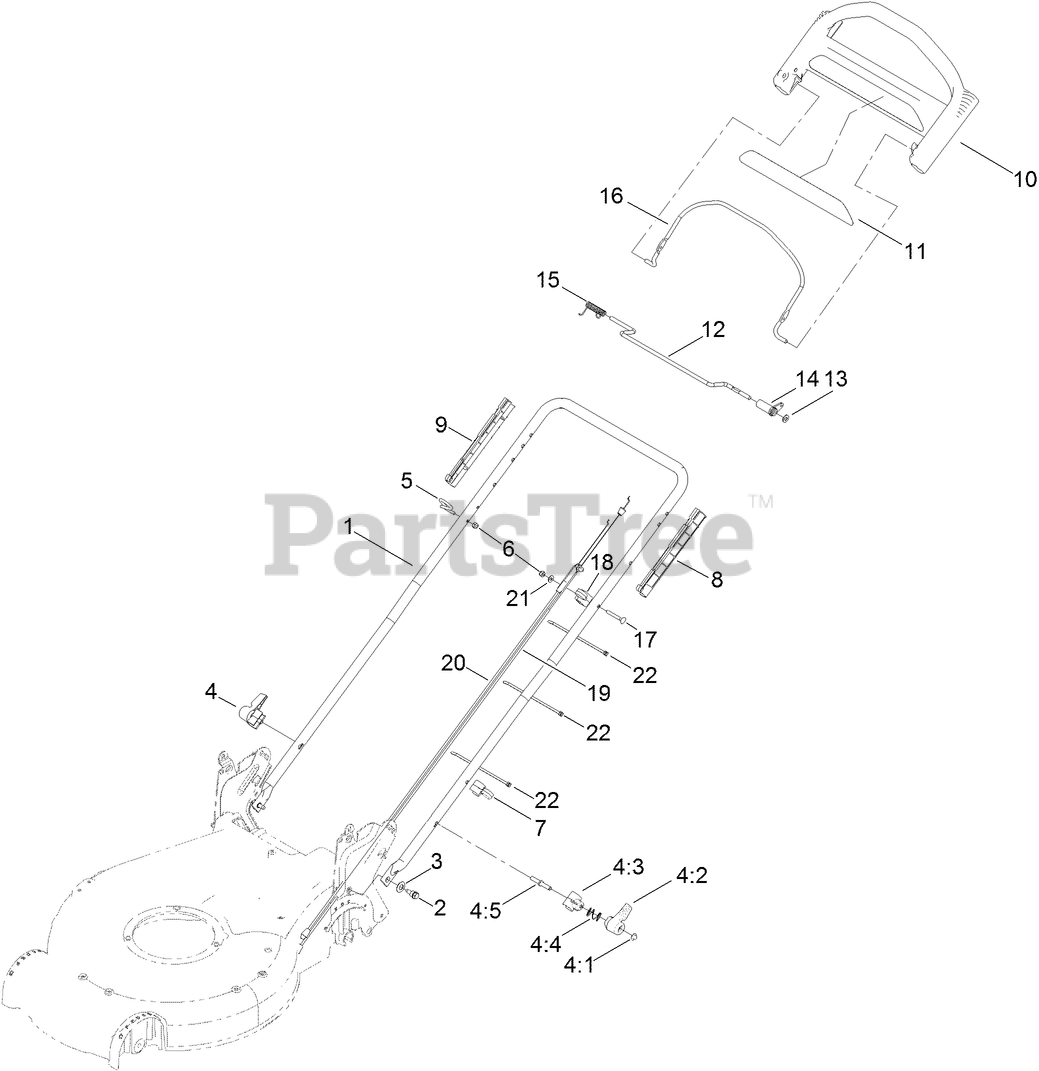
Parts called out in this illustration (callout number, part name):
2	BOLT-SHOULDER
3	WASHER-SPRING, CONICAL
4	QUICK RELEASE ASM
4:2	LEVER
4:3	ANCHOR-SPRING
4:4	SPRING-COMPRESSION
4:5	ROD-RELEASE
5	GUIDE-ROPE
6	NUT-LOCK, NI
7	GUIDE-CABLE
8	GUIDE-LH
9	GUIDE-RH
10	HANDLE-CONTROL
13	WASHER-PLAIN
14	LEVER-TRACTION
17	SCREW
19	CABLE-TRACTION
20	CABLE-BRAKE
21	WASHER-FLAT
22	TIE-CABLE
